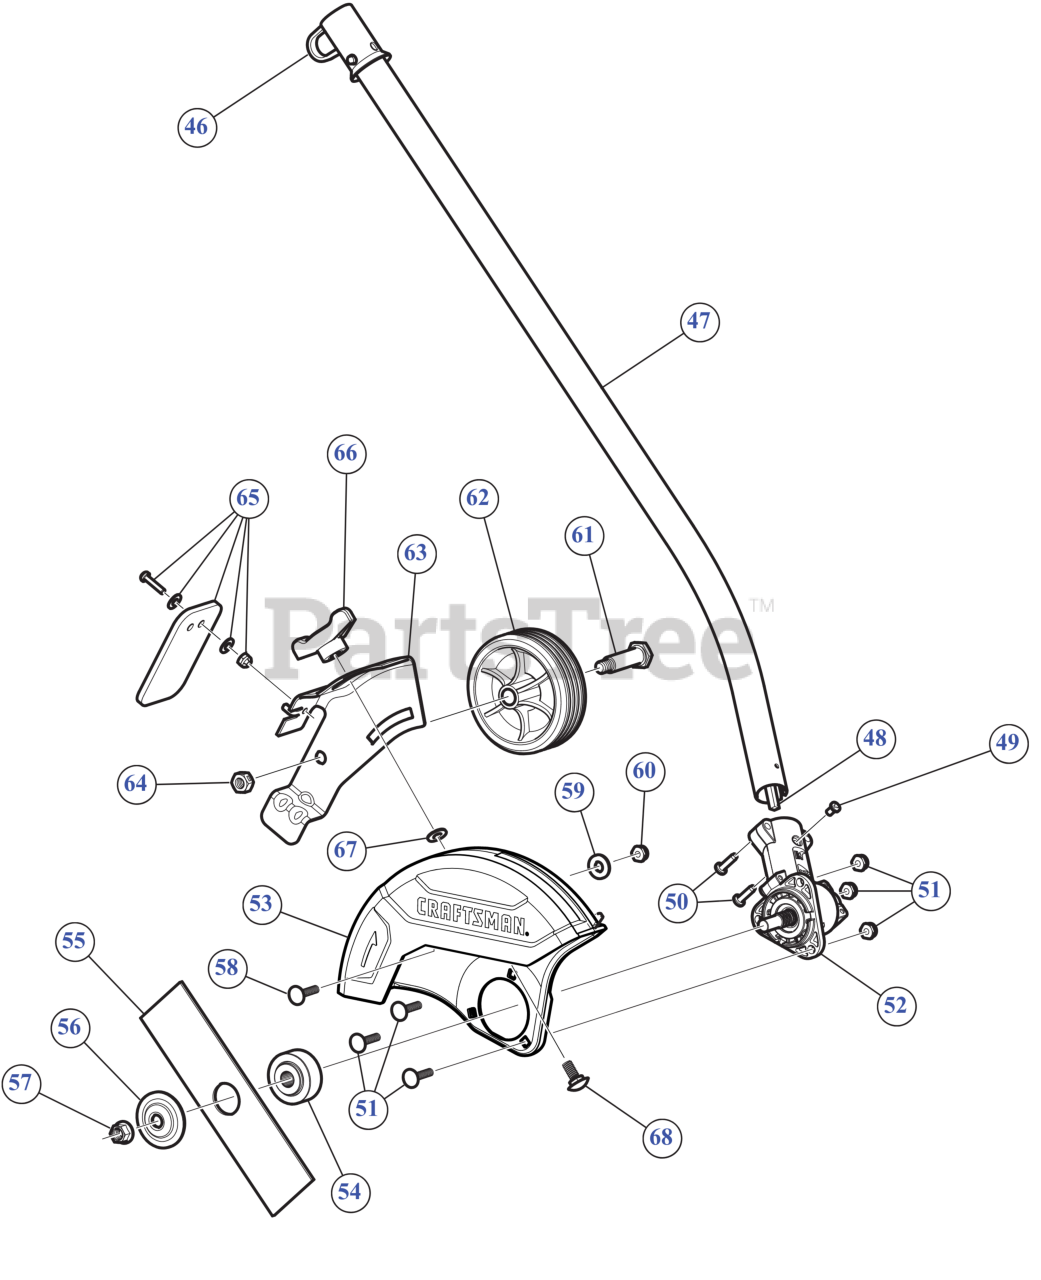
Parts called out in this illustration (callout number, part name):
46	PLUG CAP
47	BOOM ASSEMBLY
48	LOWER DRIVE SHAFT
49	SCREW, 8-32 x .312 P
50	SCREW #10-24X11/16 T-25
51	HDWR ASM:GUARD MT
52	GRBX ASSEMBLY
53	EDGER GUARD
54	SPACER
55	8" EDGER BLADE
56	WASHER-BLADE CLAMP BRUSH CUT
57	BLADE LOCK NUT
58	CARRIAGE BOLT 1/4-20 x 1
59	FLAT WASHER
60	NUT 1/4-20 NYLOC
61	SHOULDER SCREW 0.498x1.494 3/8-16
62	WHEEL 3.75" (WHITE)
63	BRACKET GUARD
64	LOCK NUT 3/8-16
65	DEFLECTOR W/HDW
66	WING KNOB 5/16-18
67	WASHER .406X1.0X.095
68	CARRIAGE BOLT 5/16-18 x .75
